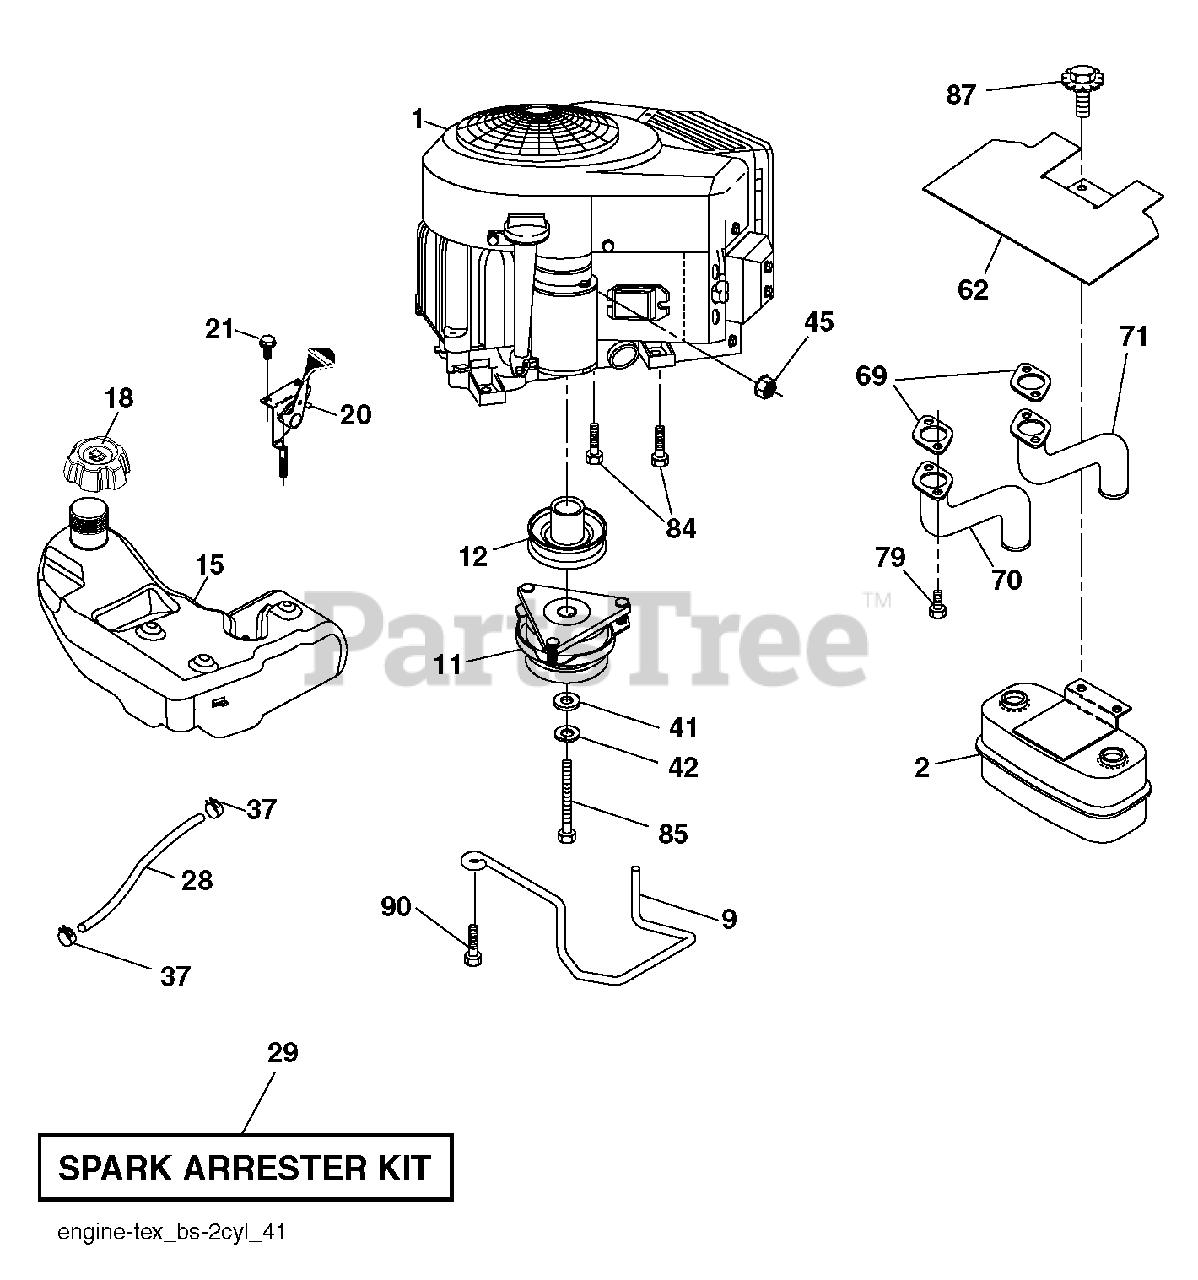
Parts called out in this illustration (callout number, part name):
2	MUFFLER.TWIN.CYL.LOW.TONE
9	KEEPER.BELT.ENGINE.4.2
11	CLUTCH.ELECTRIC.LT.48"*
12	PULLEY.ENGINE.TUFFTORQ
15	TANK.ASSY.3.GAL.EPA
18	CAP ASM.FL.RTCHT.3"GRY.E10
20	CONTROL.TH/CK.COBRA.B&S.TWN.
21	SCREW.#10 X 0.750.BOS (2 2)
28	LINE.FUEL.64"REAR.EMIS
29	KIT.SPARK ARRESTOR(392390 B&S)
37	HOSE CLAMP
42	LOCKWASHER
45	NUT
62	SHIELD.HEAT.MUFFLER
69	GASKET.MUFFLER
70	RP.EXHAUST.TUBE.LH.BS/TWIN
71	RP.EXHAUST.TUBE.RH.BS/TWIN
79	SCREW.SOCKET.HEAD.5/16-18
84	SCREW.3/8-16
85	BOLT HEX 7/16-20X4-1/4"
87	BOLT, 5/16-18 X 1 3/4
90	SCREW 3/8-16X1
